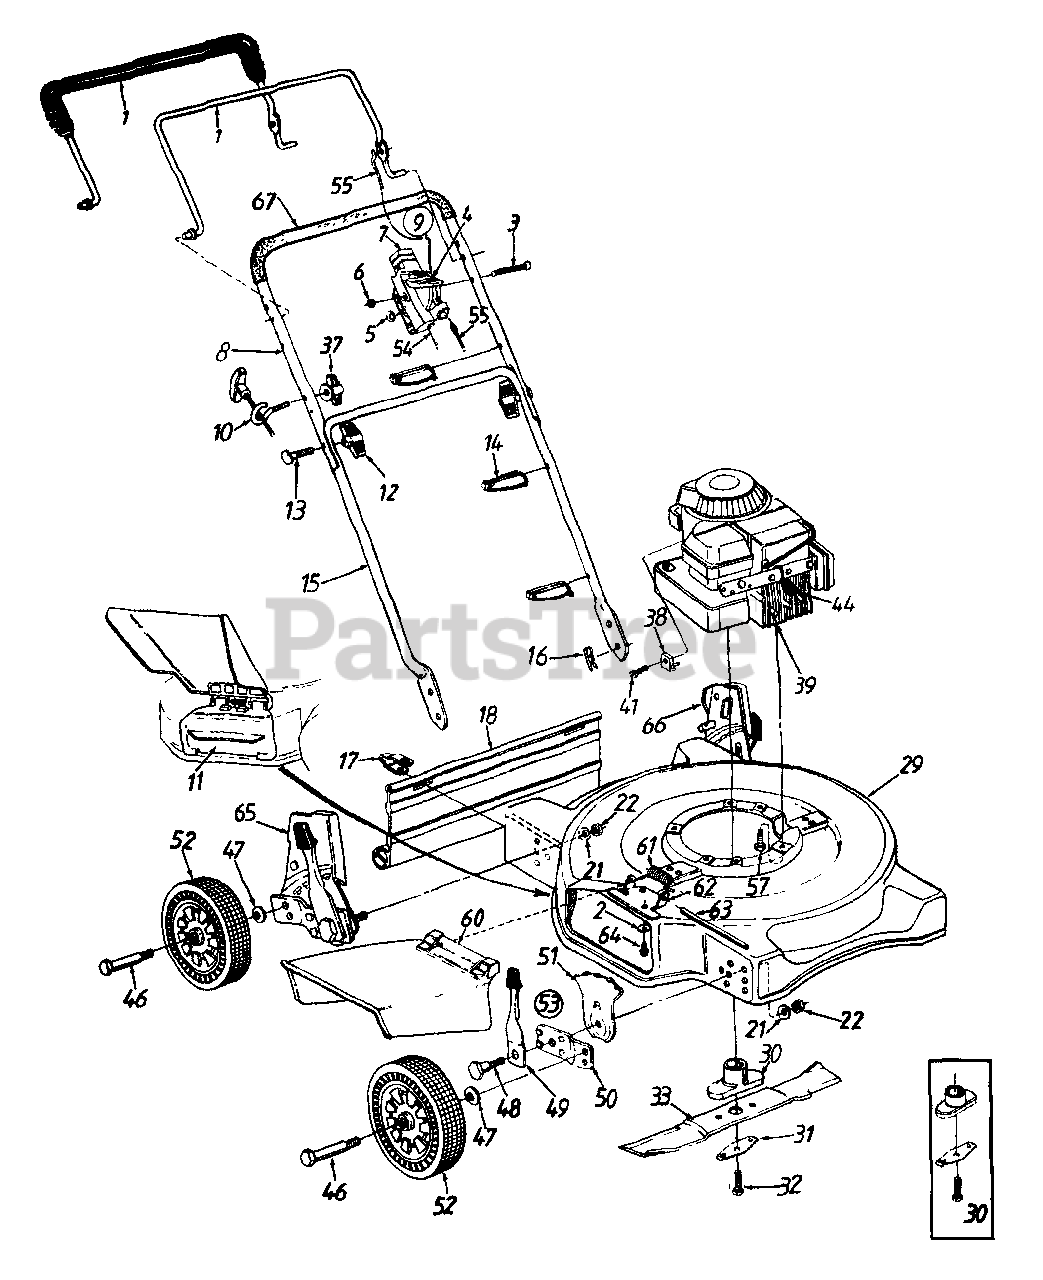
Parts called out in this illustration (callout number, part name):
2	Bell-Wash. 1/4" I.D.
3	Oval C-Sunk Mach. Scr.
4	Throttle Lever
5	Spr, Wash. .66" I.D.
6	Hex L-Nut 1/4-20 Thd.
7	Throttle Body
10	Rope Guide
11	Mulching Plug
12	Hand Knob
13	Curved Hd. Bolt 5/16-18 x 2" Lg.
14	Cable Tie
16	Hairpin Cotter
17	Hinge Clip
18	Rear Flap (20")
21	Bell-Wash. .39" I.D. x 1.38"
22	Hex Nut 3/8-16 Thd.
31	Support, Bell-Blade
32	Hex Bolt 3/8-24 x 1.5" Lg.
33	20" Blade
37	Wing Nut 1/4-20 Thd.
38	Cable Clamp
39	Engine
41	Hex Wash. Hd. Tap Scr. #10-32 x .62 Lg.
44	Spark Plug Boot
46	Axle Bolt
47	Bell-Wash. .400" I.D. x .88"
48	Shld. Bolt .50" Dia. x .357"
49	Spring Lever Ass'y. w/Knob
51	Height Adj. Plate
52	Wheel Assembly Complete
53	Height Adj. Ass'y. Comp.-R.F.
54	Throttle Cable-51"
55	Control Cable-39"
57	Hex L-Wash. Hd. Scr. 3/8-16 x 1.0" Lg.
60	Chute Deflector Ass'y.
61	Torsion Spring
62	Adapter Plate
63	Hinge Pin
64	Hex Self-Tap Scr. 1/4-20 x .5"
67	Foam Grip
